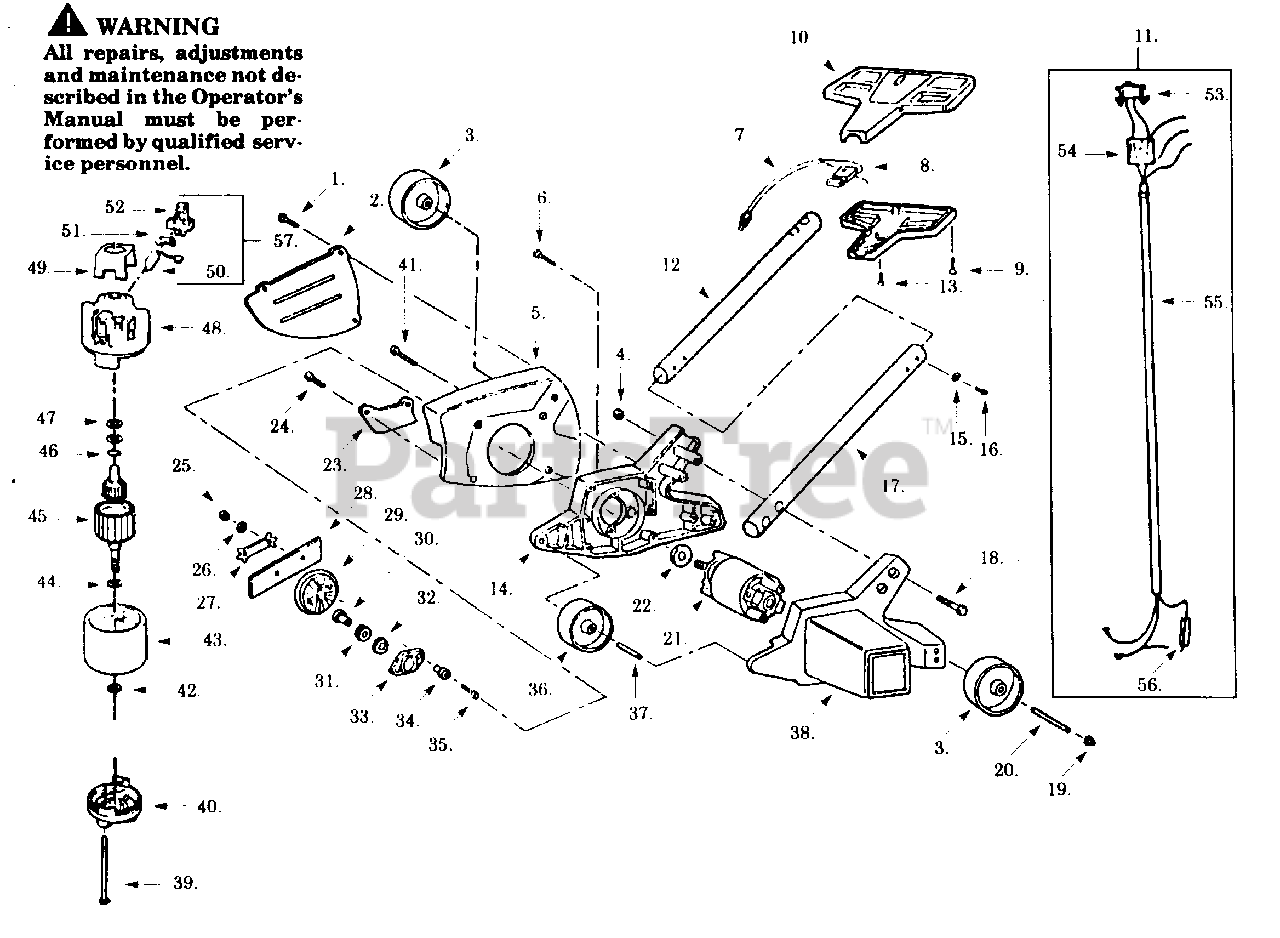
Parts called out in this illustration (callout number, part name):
2	Side Guard
4	Locknut
5	Guard Housing
7	Power Cord
8	Trigger Switch
10	Handle Set
11	Harness Ass'y.
12	Upper Handle Tube
15	Lockwasher
17	Lower Handle Tube
19	Push Nut
22	Thrust Washer
23	Edge Guide
26	Lockwasher
27	Lock Strap
30	Clutch Sleeve
31	Load Spring Washer
33	Clutch Plate
38	Motor Cover
40	Endbell (Output)
43	Field Ass'y.
44	Retainer Ring
45	Armature
46	Retainer Ring
48	Endbell (Brush)
49	Insulator
51	Brush Spring
52	Brush Holder
53	Power Switch
54	P.C. Bridge Kit
56	Resistor
